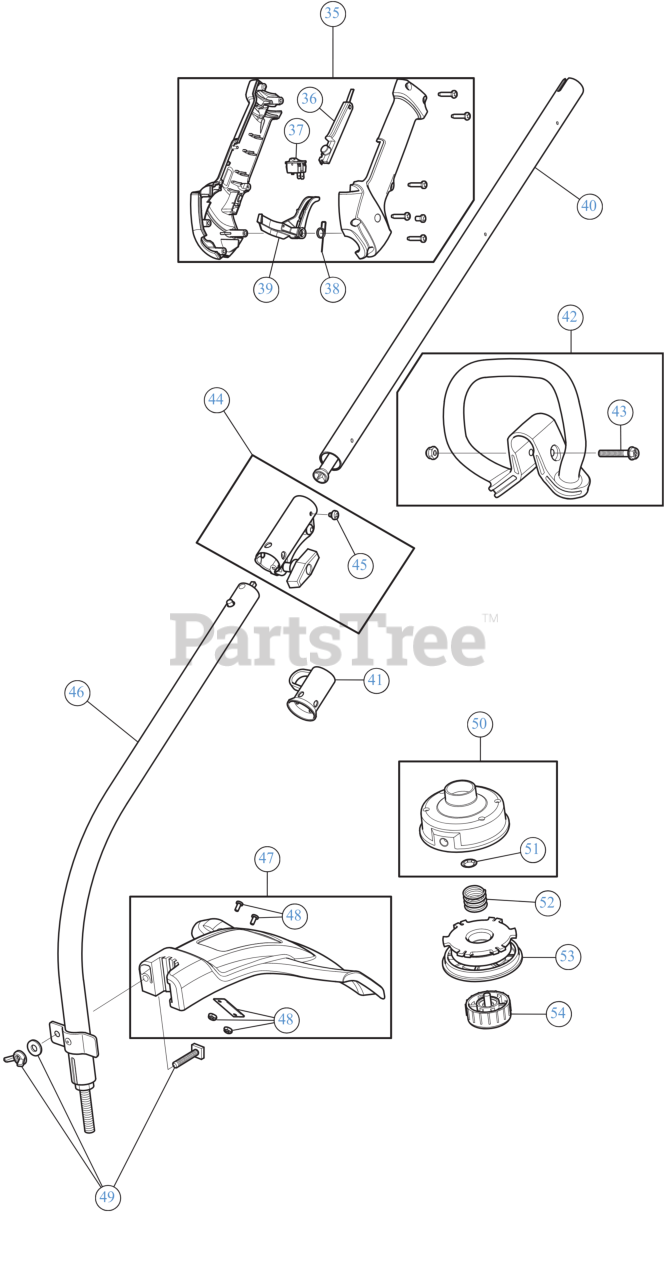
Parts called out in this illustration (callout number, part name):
35	THROTTLE GRIP ASSEMBLY
36	LEVER LOCK OUT
37	SW, MOMENTARY ON/O
38	SPRING TRIG
38	THROTTLE TRIGGER
40	BOOM ASSEMBLY UPR
41	HANGER
42	D-HANDLE
43	BOLT 1/4-20X1 1/2
44	COUPLER ASSEMBLY
45	SCREW, 10-32X.250 TA
46	BOOM ASSEMBLY W/FLEX DRIVE SHAFT
47	GUARD ASSEMBLY
48	ASSEMBLY, BLADE
49	BLADE GUARD MOUNTING HARDWARE
50	REEL:OTR W/RET
51	RETAINER .625 OD 2
52	SPRING-SPOOL
53	REEL-INNER SPOOL
54	BUMP KNOB (LIB RED)
